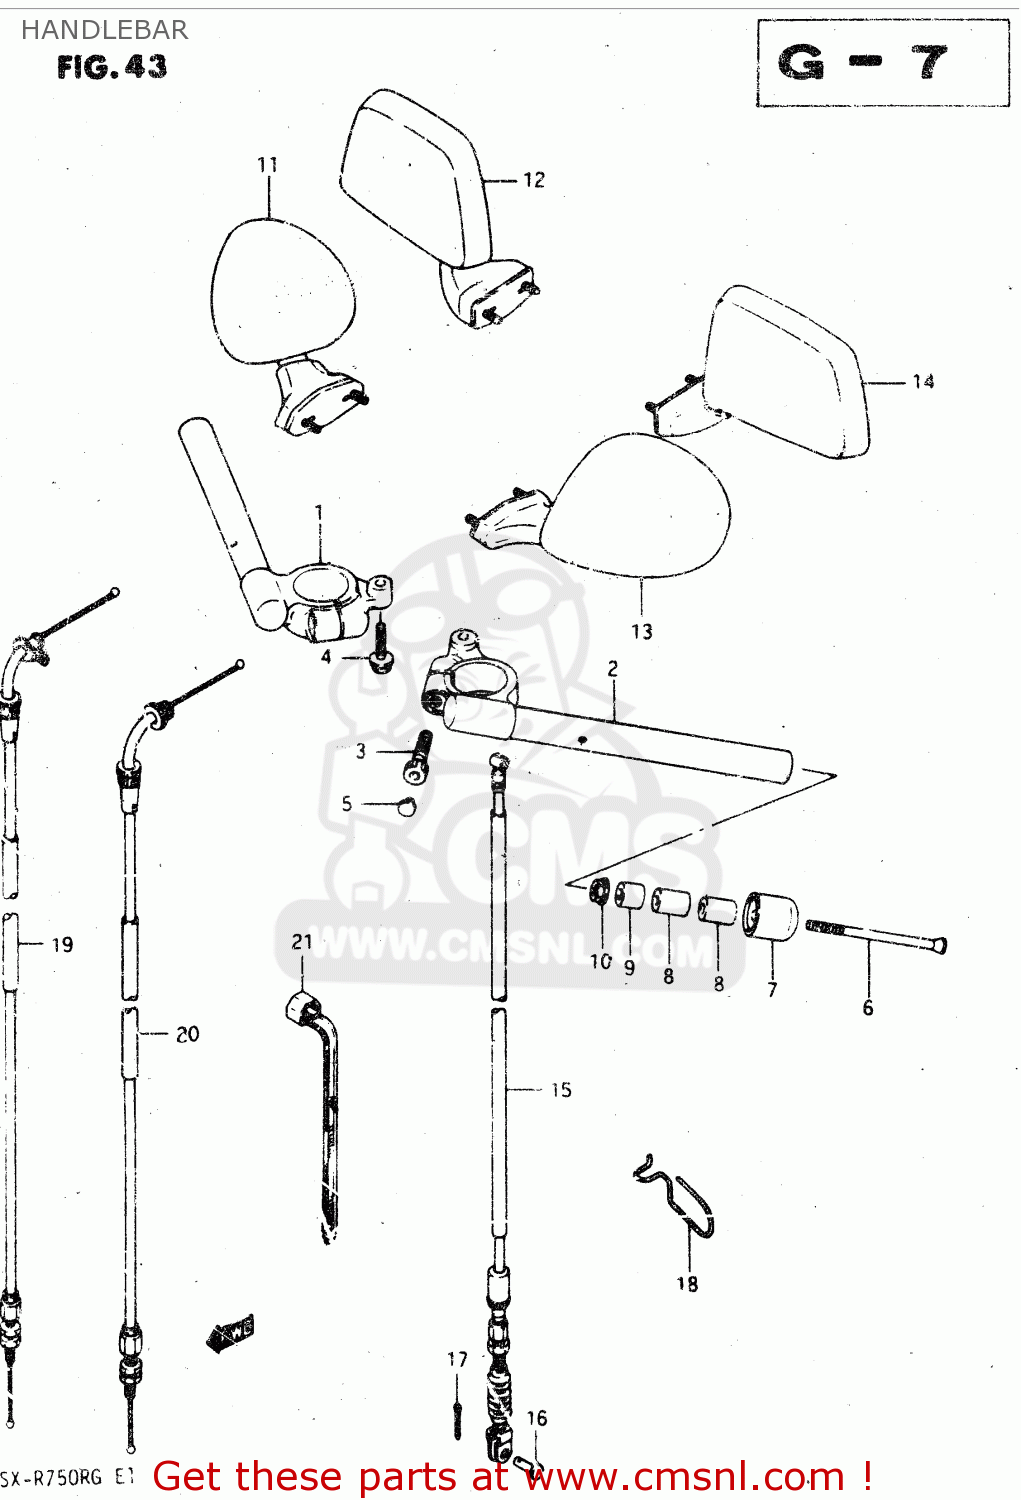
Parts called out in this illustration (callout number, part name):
1	HANDLEBAR,RIGHT
2	HANDLEBAR,LEFT
3	BOLT, HANDLEBAR
4	BOLT
5	CAP(OD:10)
6	SCREW(6X85)
7	CAP,BALANCER
8	BALANCER,HANDLEBAR INNER
9	EXPANDER,HANDLE BALANCER
10	NUT
11	MIRROR ASSEMBLY,RIGHT
12	MIRROR ASSY,RH
13	MIRROR ASSEMBLY,LEFT
14	MIRROR ASSY,LH
15	CABLE ASSY,CLUTCH
16	PIN(L:15)
17	PIN
18	GUIDE, CLUTCH CABLE
19	CABLE ASSY, THROTTLE NO.2
20	CABLE ASSY, THROTTLE NO.2
21	CLAMP(L:165)
